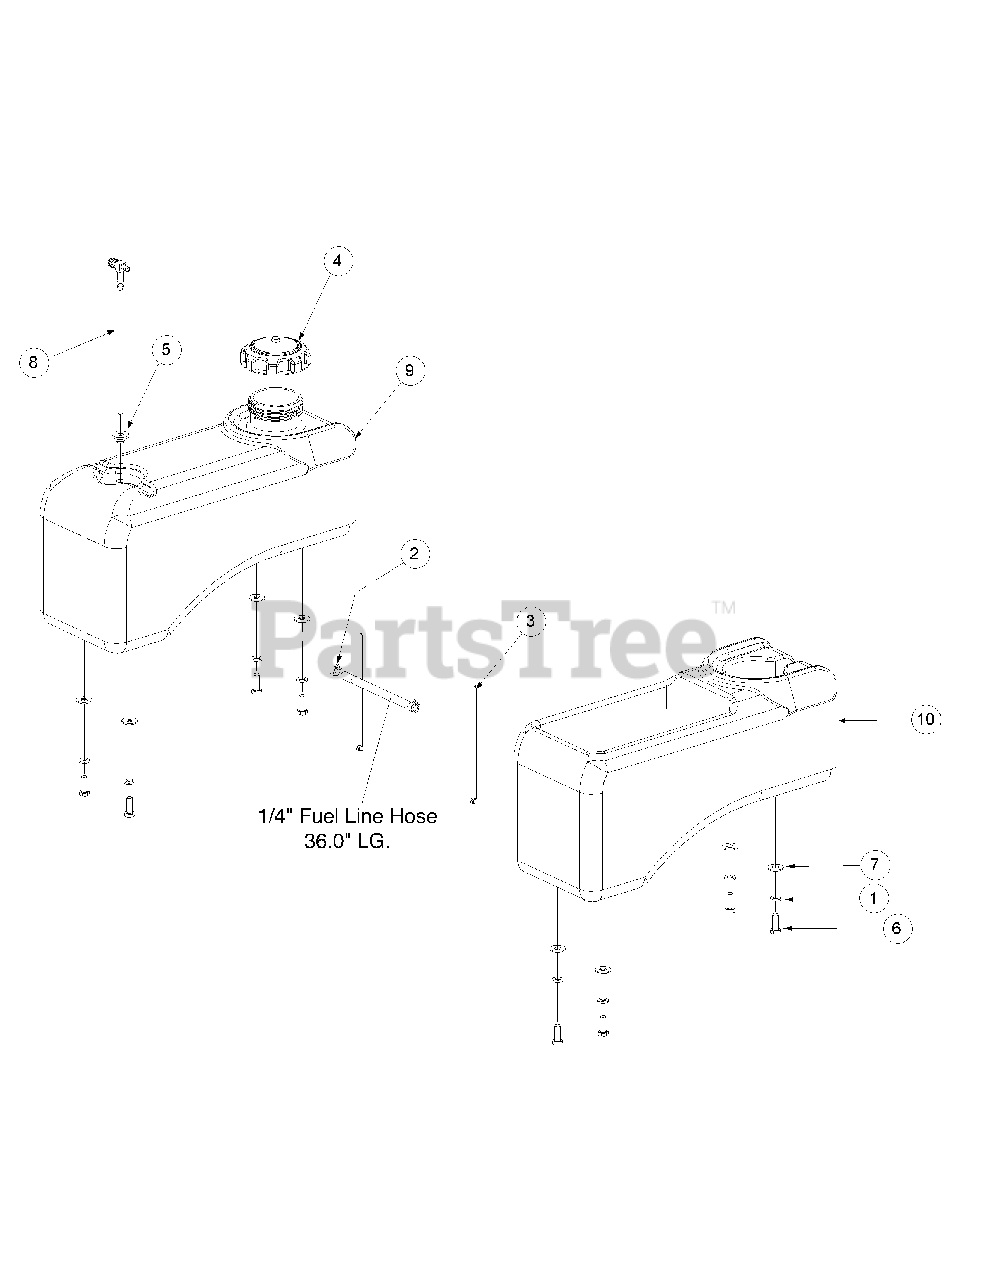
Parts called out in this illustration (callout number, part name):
1	Lock Washer, 3/8
2	Clamp, Union
3	Cable Tie
4	Fuel Cap, 3.5
5	Grommet, Fuel Tank
6	Hex, Cap Screw, 3/8-16, .88
7	Flat Washer, .406 ID, 1.0 OD, .105
8	Fuel Fitting
9	Fuel Tank
10	Utility Bin
11	Hose, 1/4" Fuel Line (36 inches)
